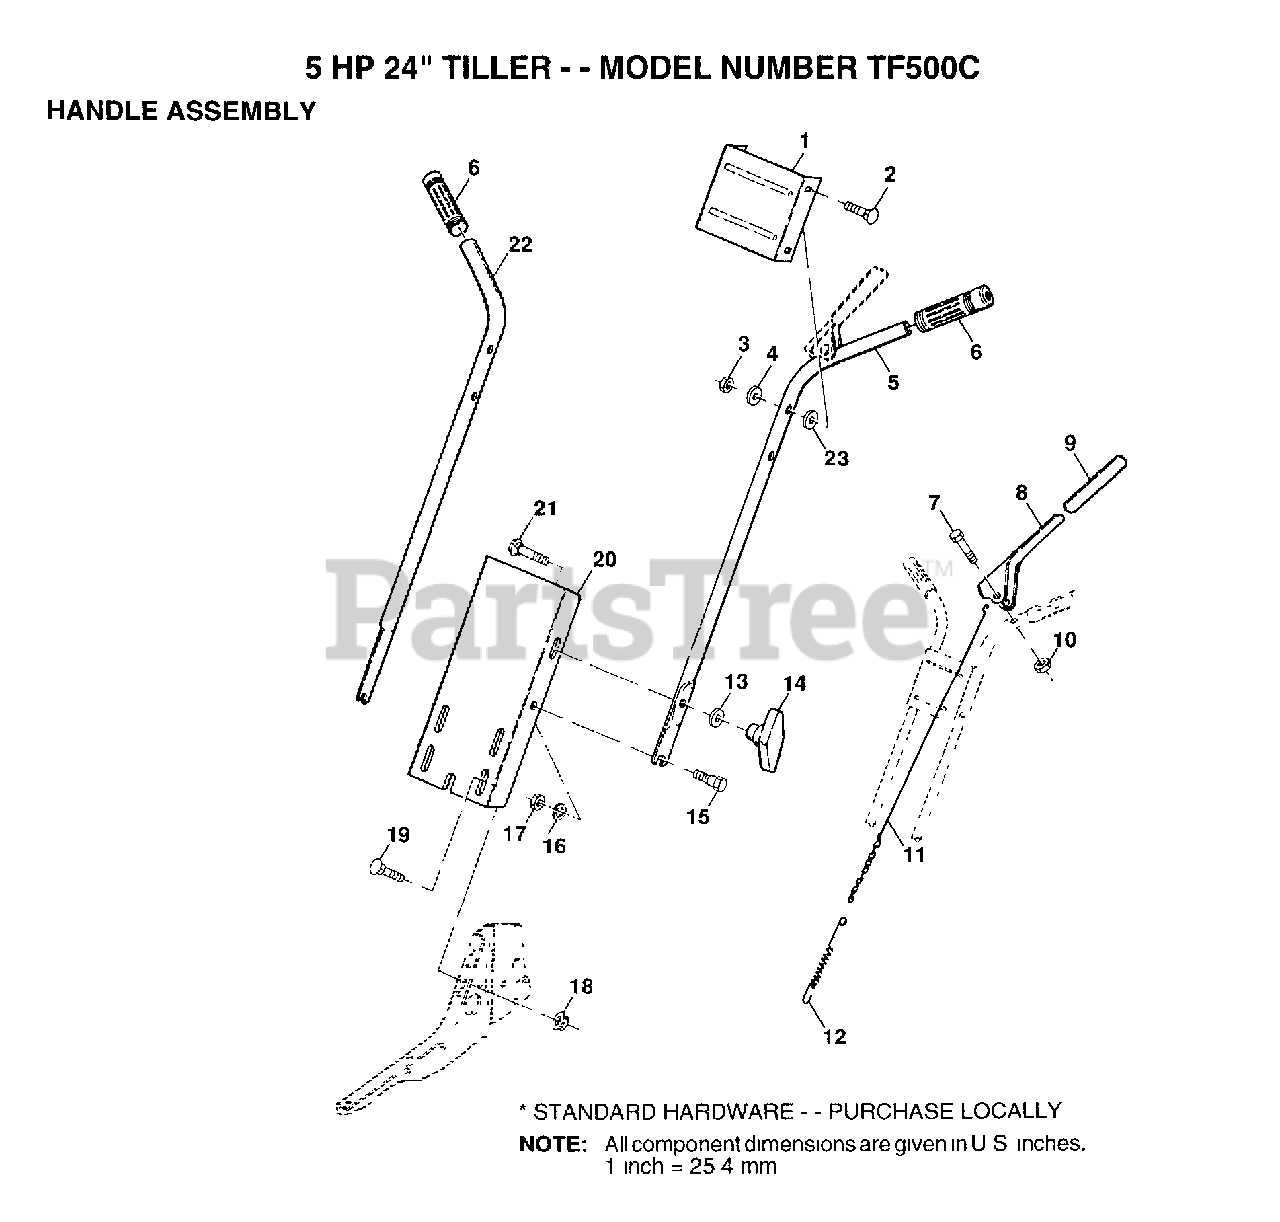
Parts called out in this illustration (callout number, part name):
2	BOLT
4	WASHER
7	BOLT.HEX.5/16-1.5
9	GRIP T
12	SPRING EXT TI
13	WASHER
14	KNOB HANDLE
16	LOCKWASHER
17	NUT.HEX.5/16-18
18	NUT
19	BOLT
21	BOLT
23	WASHER
